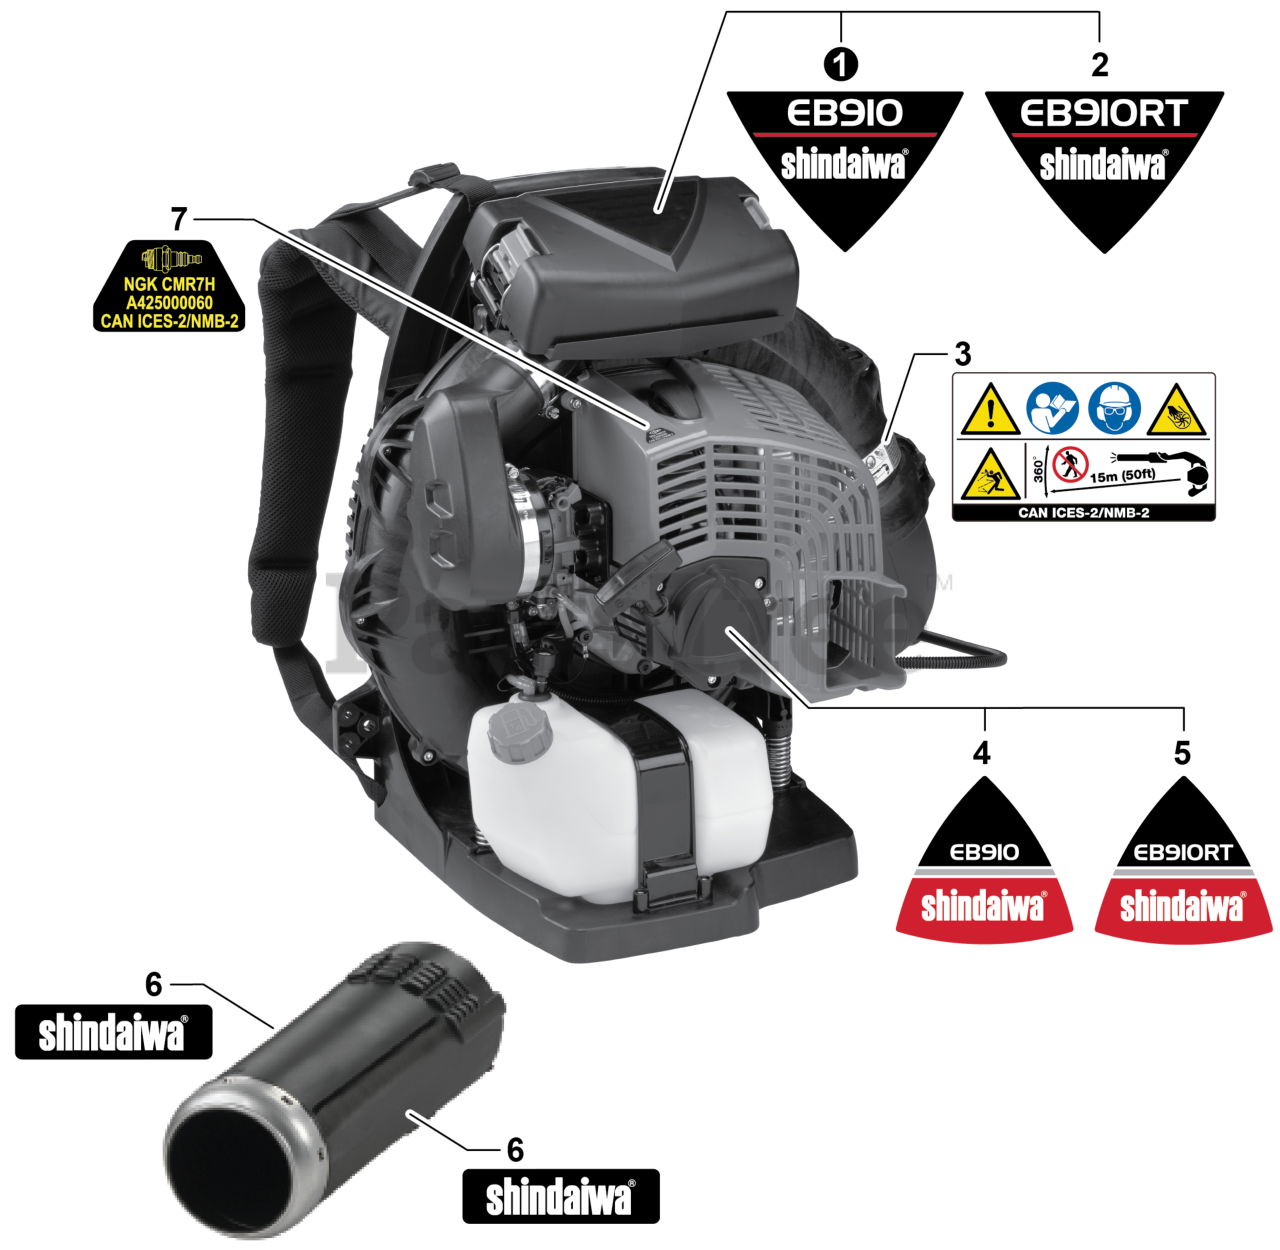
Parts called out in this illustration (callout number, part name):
1	LABEL - EB910
2	LABEL - EB910RT
3	LABEL - CAUTION
4	LABEL - EB910
5	LABEL - EB910RT
6	LABEL - SHINDAIWA BLOWER TUBE
7	LABEL - SPARK PLUG - CMR7H
